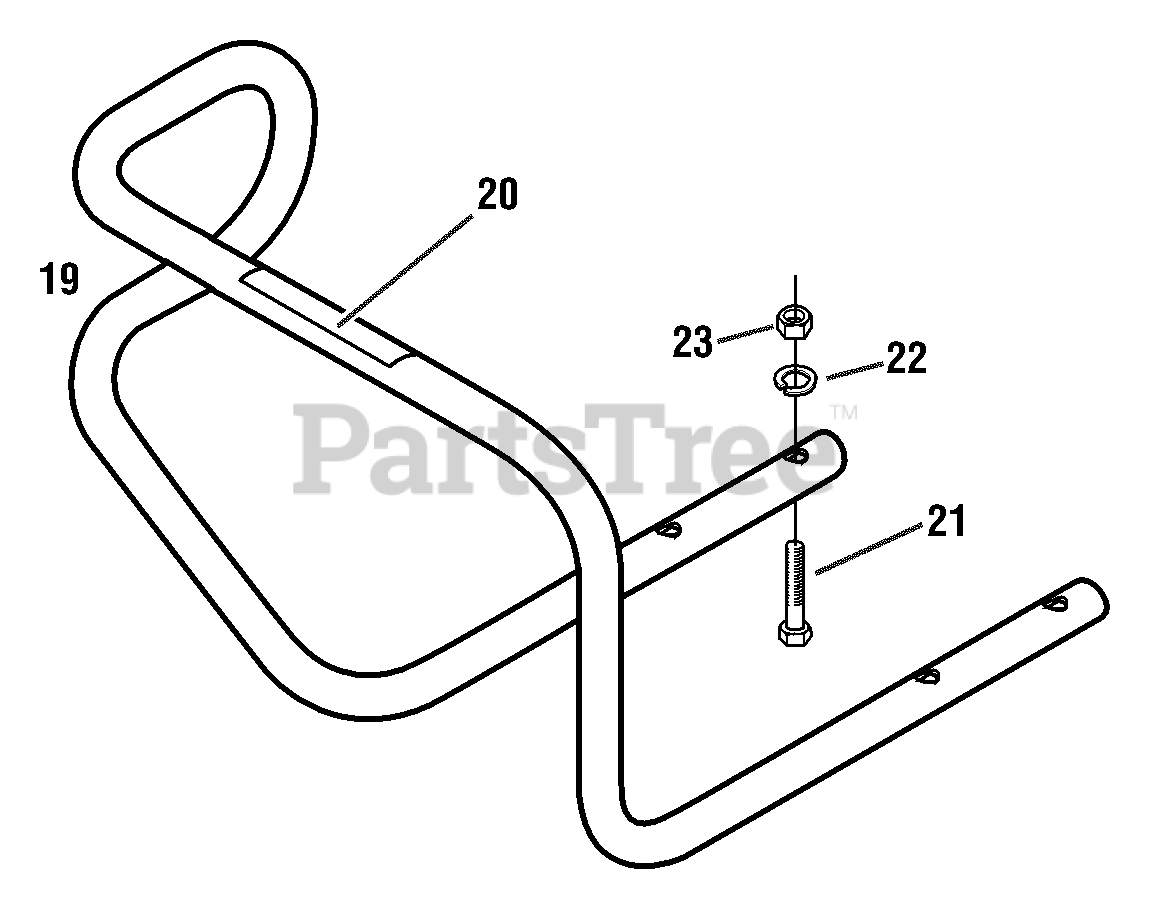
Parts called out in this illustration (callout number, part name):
19	Bumper
20	Decal - Caution
21	Screw-hex hd., 5/16-18 x 2-1/4, not avail. separately (order #1918781 hardware kit)
22	Lockwasher-5/16, not avail. separately (order #1918781 hardware kit)
23	Nut-hex, 5/16-18, not avail. separately (order #1918781 hardware kit)
